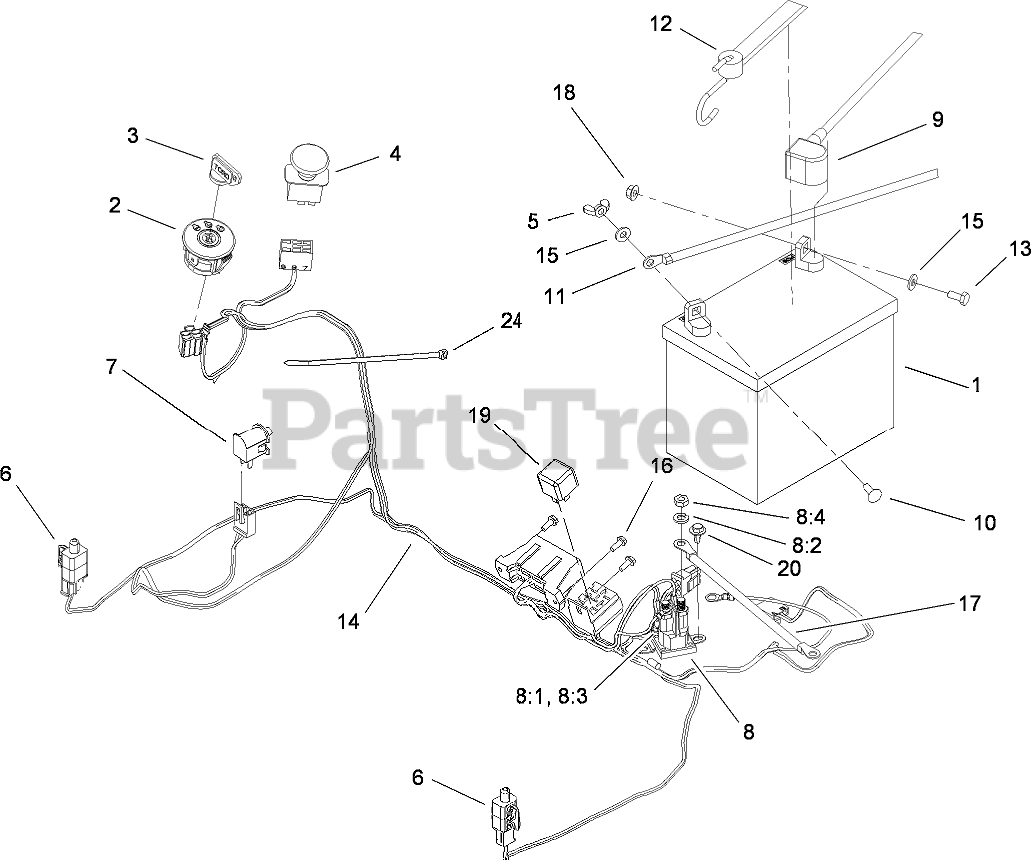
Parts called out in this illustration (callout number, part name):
1	BATTERY
2	SWITCH-IGNITION
3	KEY-IGNITION
4	SWITCH-PTO
5	NUT-WING
6	SWITCH
7	SWITCH-BAIL
8	SWITCH-SOLENOID
8:1	WASHER-LOCK
8:2	WASHER-LOCK
8:3	NUT-HEX
8:4	NUT-JAM
9	CABLE-BATTERY, RED
10	BOLT-CARR
11	CABLE-BATTERY, BLACK
12	HOLDDOWN-BATTERY
13	SCREW-HH
14	HARNESS-WIRE
15	WASHER-FLAT
16	SCREW-TAPTITE
17	CABLE-BATTERY, RED
18	NUT-HF
19	RELAY
20	SCREW-HHFTF
24	TIE-CABLE
